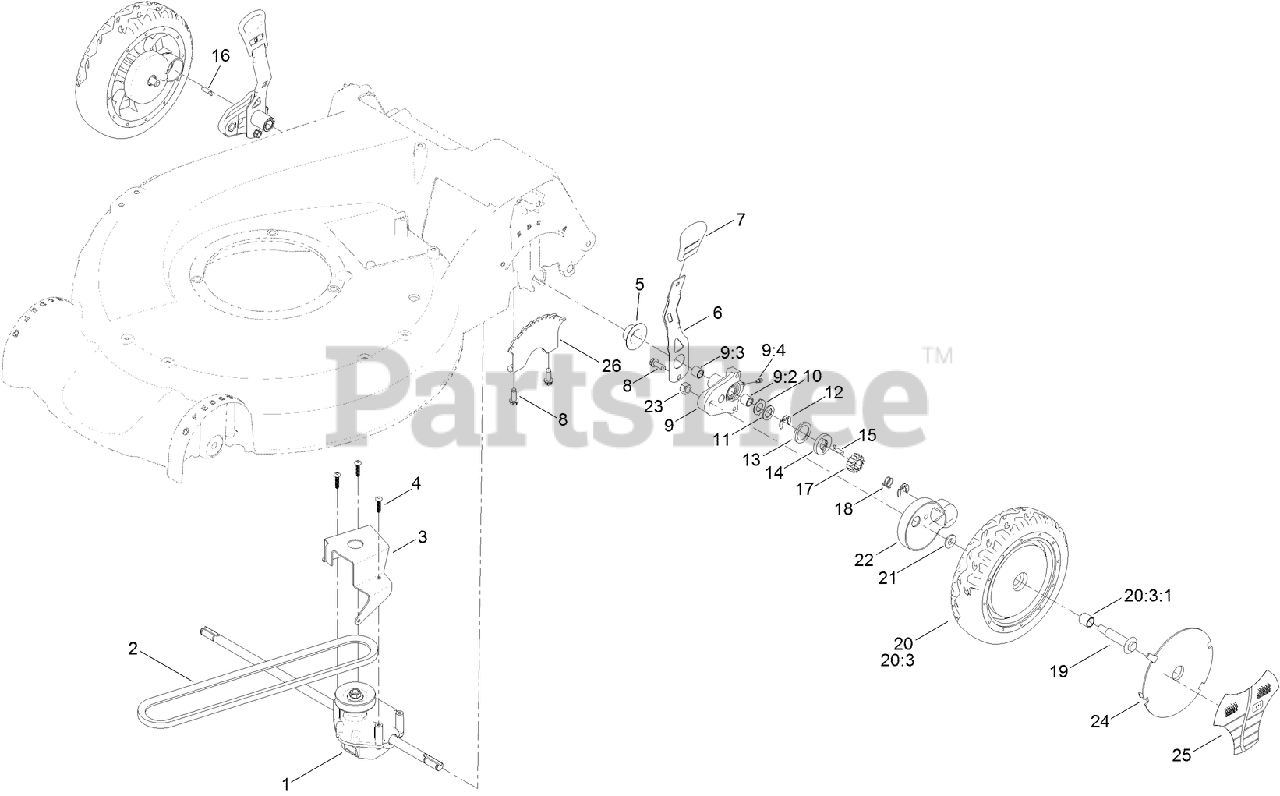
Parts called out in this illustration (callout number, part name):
1	TRANSMISSION ASM
2	V-BELT
3	BRACKET-TRANSMISSION
4	SCREW-PLASTITE
5	CAP-END
6	ARM-SPRING
7	KNOB-HOC
8	SCREW-HWHTF
9	PIVOT ARM ASM
9:2	BUSHING
9:3	BUSHING
9:4	FITTING-GREASE
10	WASHER-ARM, PIVOT
11	WASHER-THRUST, KEYED
12	RING-RETAINING,CLIP
13	RING-FRICTION
14	WASHER-CLUTCH
15	KEY-ROCKING, LH
16	KEY-ROCKING, RH
17	GEAR-PINION
18	SPRING-COMPRESSION
19	BOLT-SHOULDER
20	8 INCH WHEEL AND GEAR ASM
20:3	Loose Parts Package
20:3:1	BUSHING
21	SPACER-COVER, WHEEL
22	COVER-WHEEL
23	NUT-HEX
24	COVER-WHEEL
25	LABEL-WHEEL, SMART
26	PLATE-HOC
